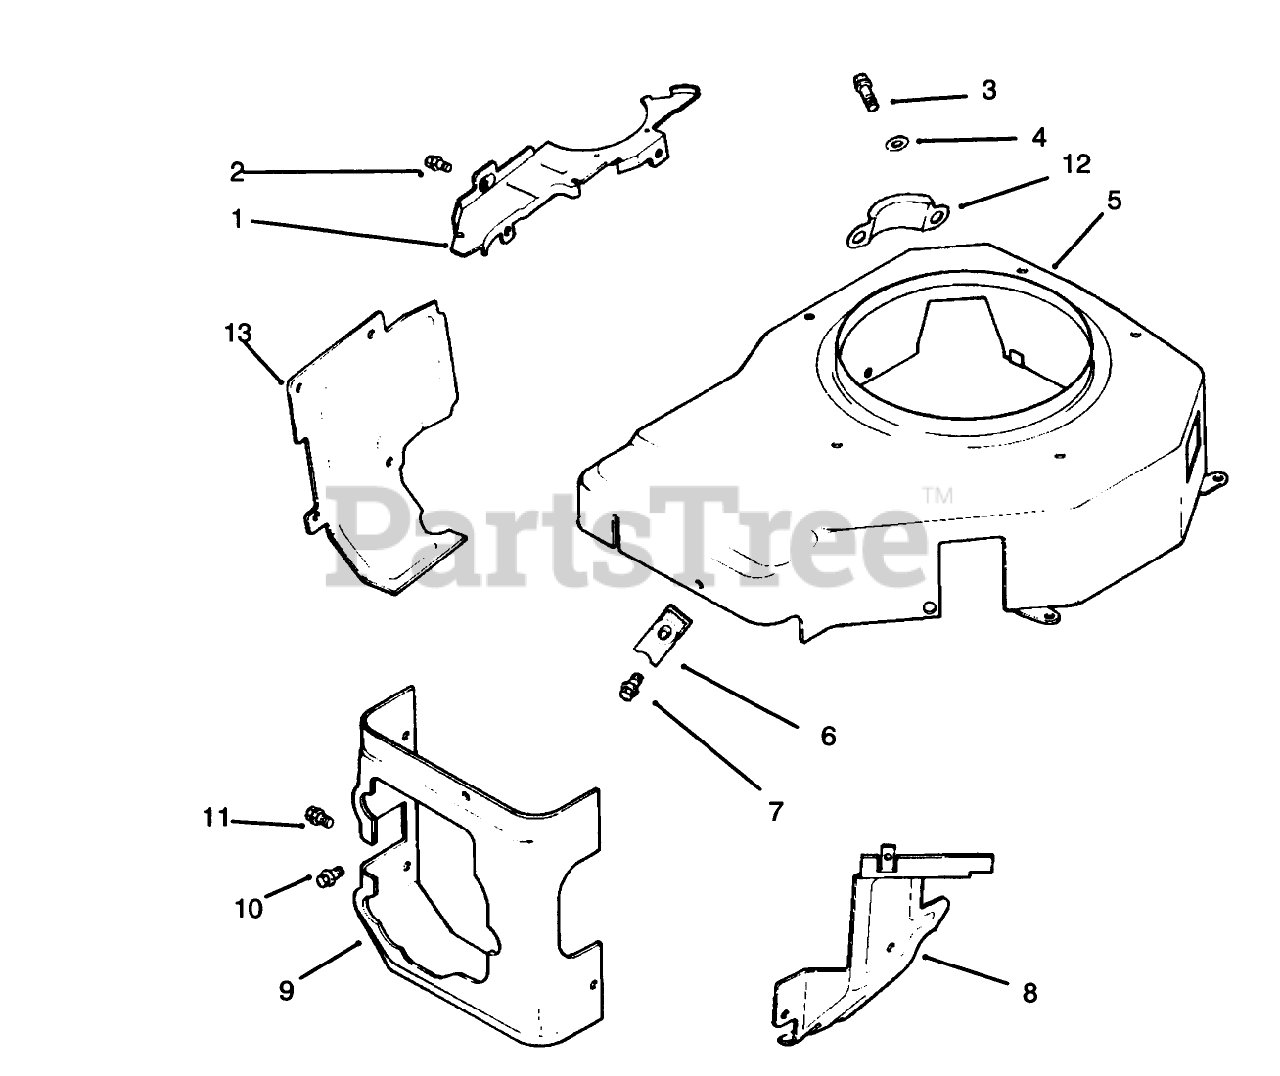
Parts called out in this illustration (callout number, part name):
1	Plate-Blower Housing (Only On: 72042,72043,72062,72063)
4	Washer
5	Housing-Blower
8	Baffle-Carburetor (Only On: 72042, 72043, 72062, 72063)
9	Baffle-Cylinder Head (Only On: 72042, 72063, 72062, 72043)
12	Cover-Pinion
13	Baffle-Cylinder Barrel (Only On: 72042, 72063, 72062, 72043)
